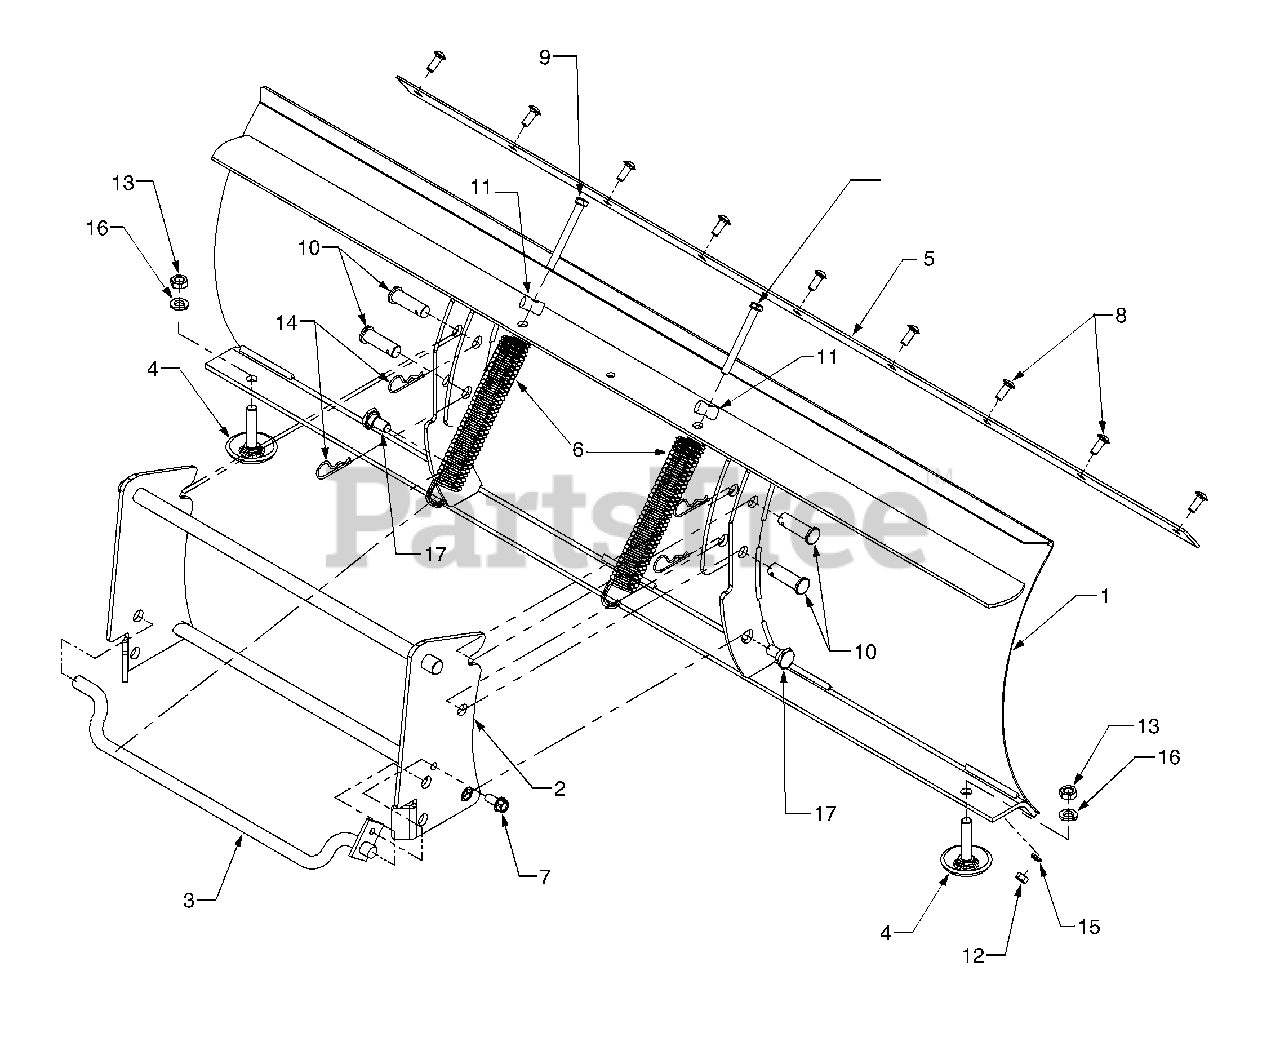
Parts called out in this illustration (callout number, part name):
7	Screw, Hex Wash. Hd.Tap Screw 3/8-16 x .75
8	Bolt, Carriage 5/16-18 x 7/8 Lg.
9	Bolt, Hex, 3/8-16 x 3.5" Lg.
10	Pin, Clevis
11	Roller, Spring
12	Nut, Hex 5/16-18 Thd, Gr.5
13	Nut, Jam 1/2-13 Thd. Gr. 5
14	Pin, Internal, Cotter
15	Washer, Lock 5/16" I.D.
16	Washer, Lock 1/2" I.D.
17	Screw, Shoulder
